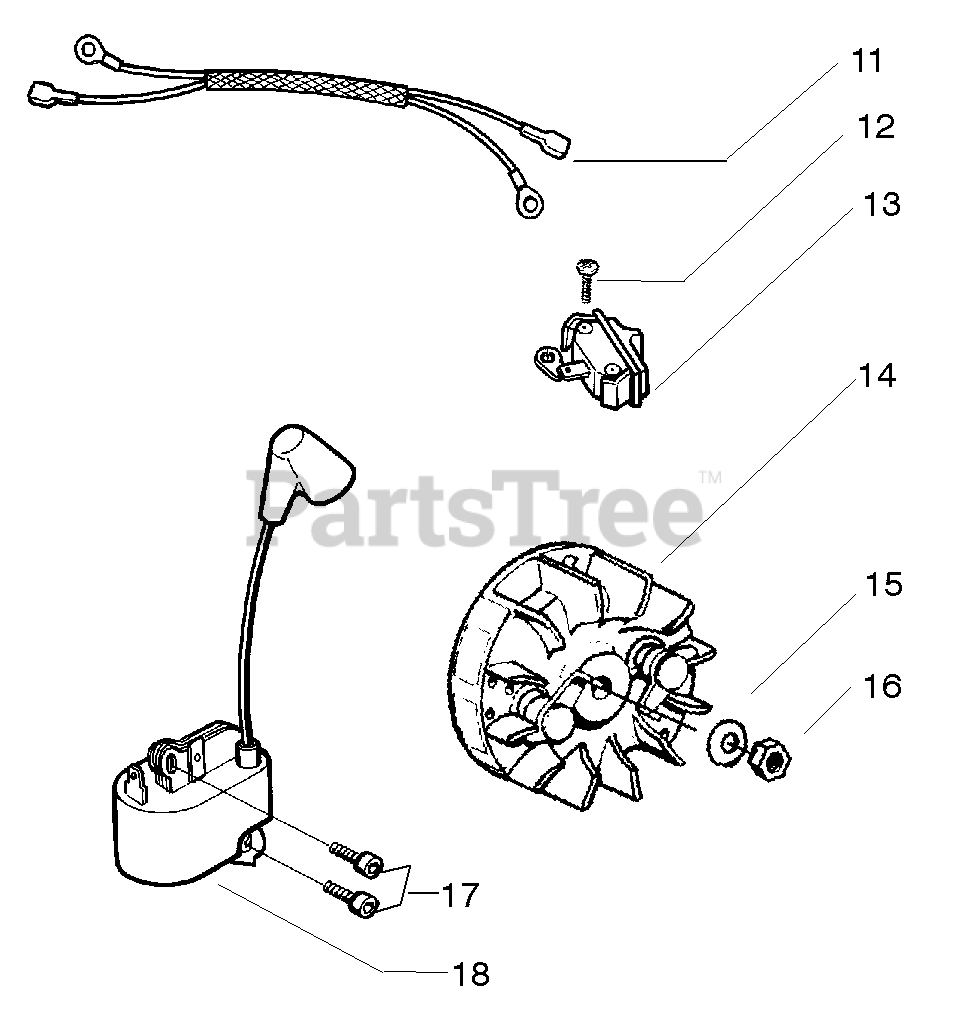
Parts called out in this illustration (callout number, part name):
11	Assy-Leadwire Harness
13	Switch-Ignition
14	Assy. -Flywheel
15	Washer-Flywheel
18	Module - Ignition
